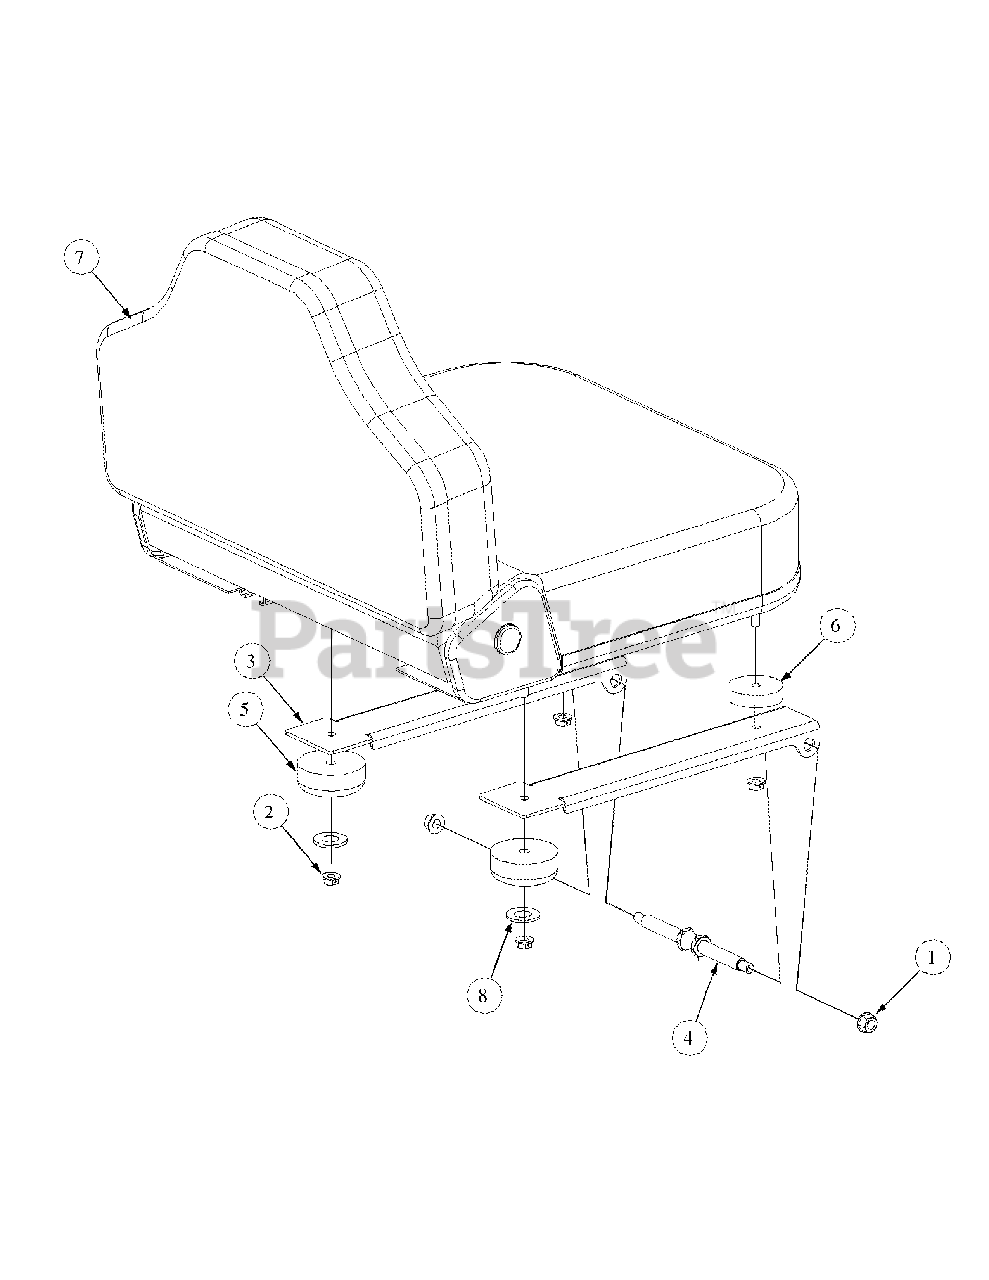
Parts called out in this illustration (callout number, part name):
1	Nut, Hex 3/8-16 Flange Lock
2	Lock Nut, Hex Flange, 5/16-18
3	Mounting Bracket, Seat
4	Shoulder Screw, .50x2.345, 3/8-16
5	Grommet, 2.5 OD x 1.0 Long
6	Spacer, .406 ID x 1.00 OD x .38
7	Adjustable Seat, Black
8	Flat Washer, .406 ID, 1.00 OD, .105
